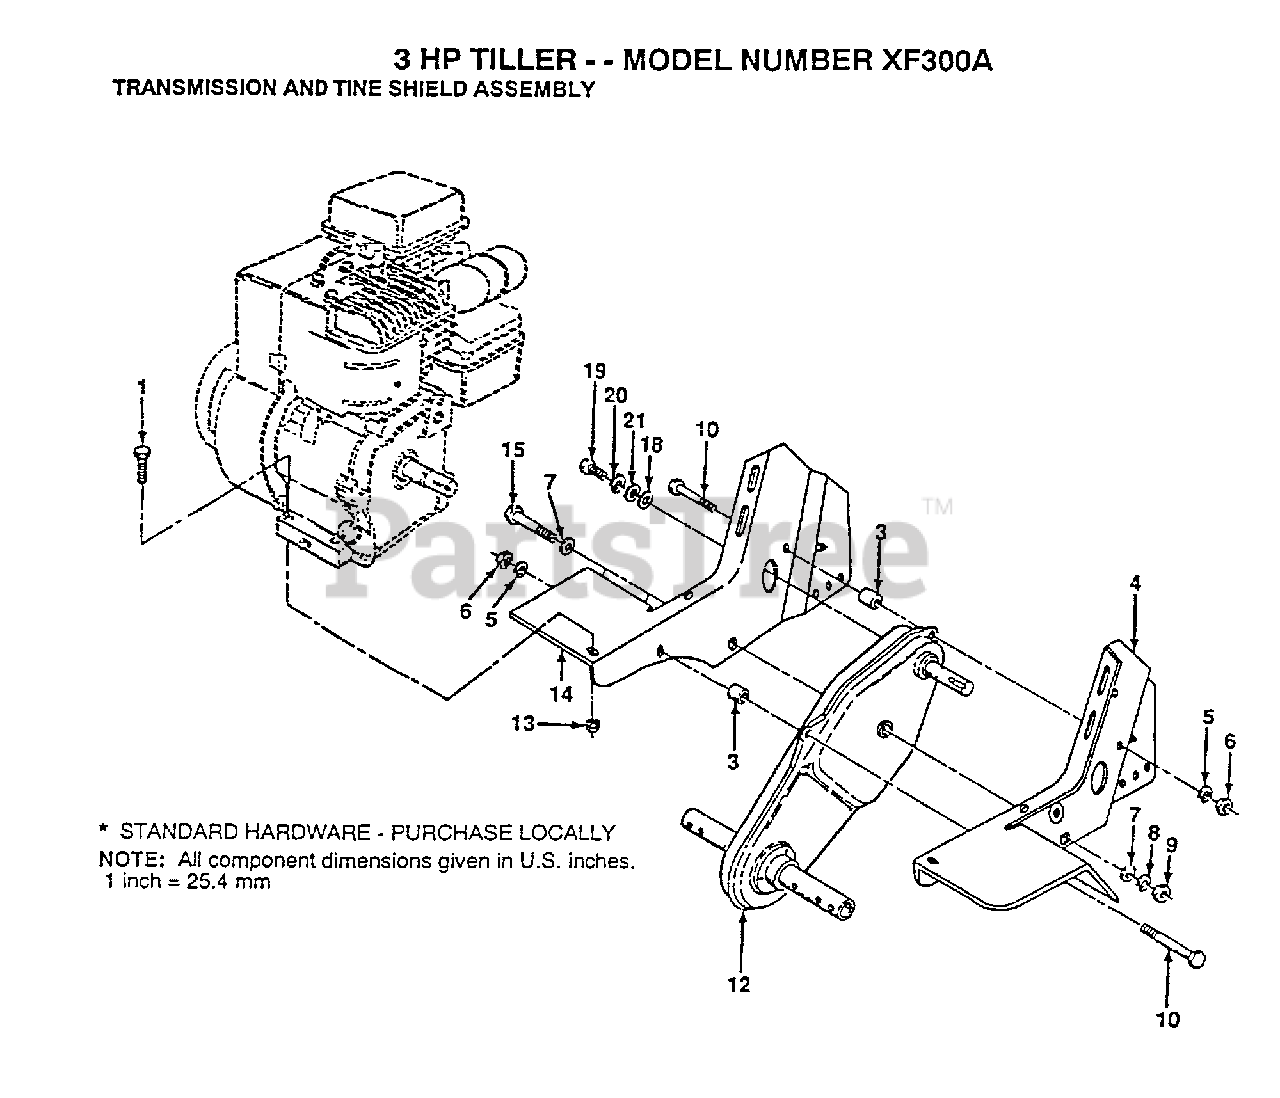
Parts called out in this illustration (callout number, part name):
1	BOLT.HEX.5/16-1.5
3	SPLIT SPACER RT
4	"BRKT,ENG LH "
5	LOCKWASHER
6	NUT.HEX.5/16-18
7	WASHER
8	LOCKWASHER
9	GRIPCO NUT
14	"BRKT,ENG RH"
15	BOLT.3/8-24X3.75
18	WASHER
19	BOLT
20	LOCKWASHER
21	WASHER
